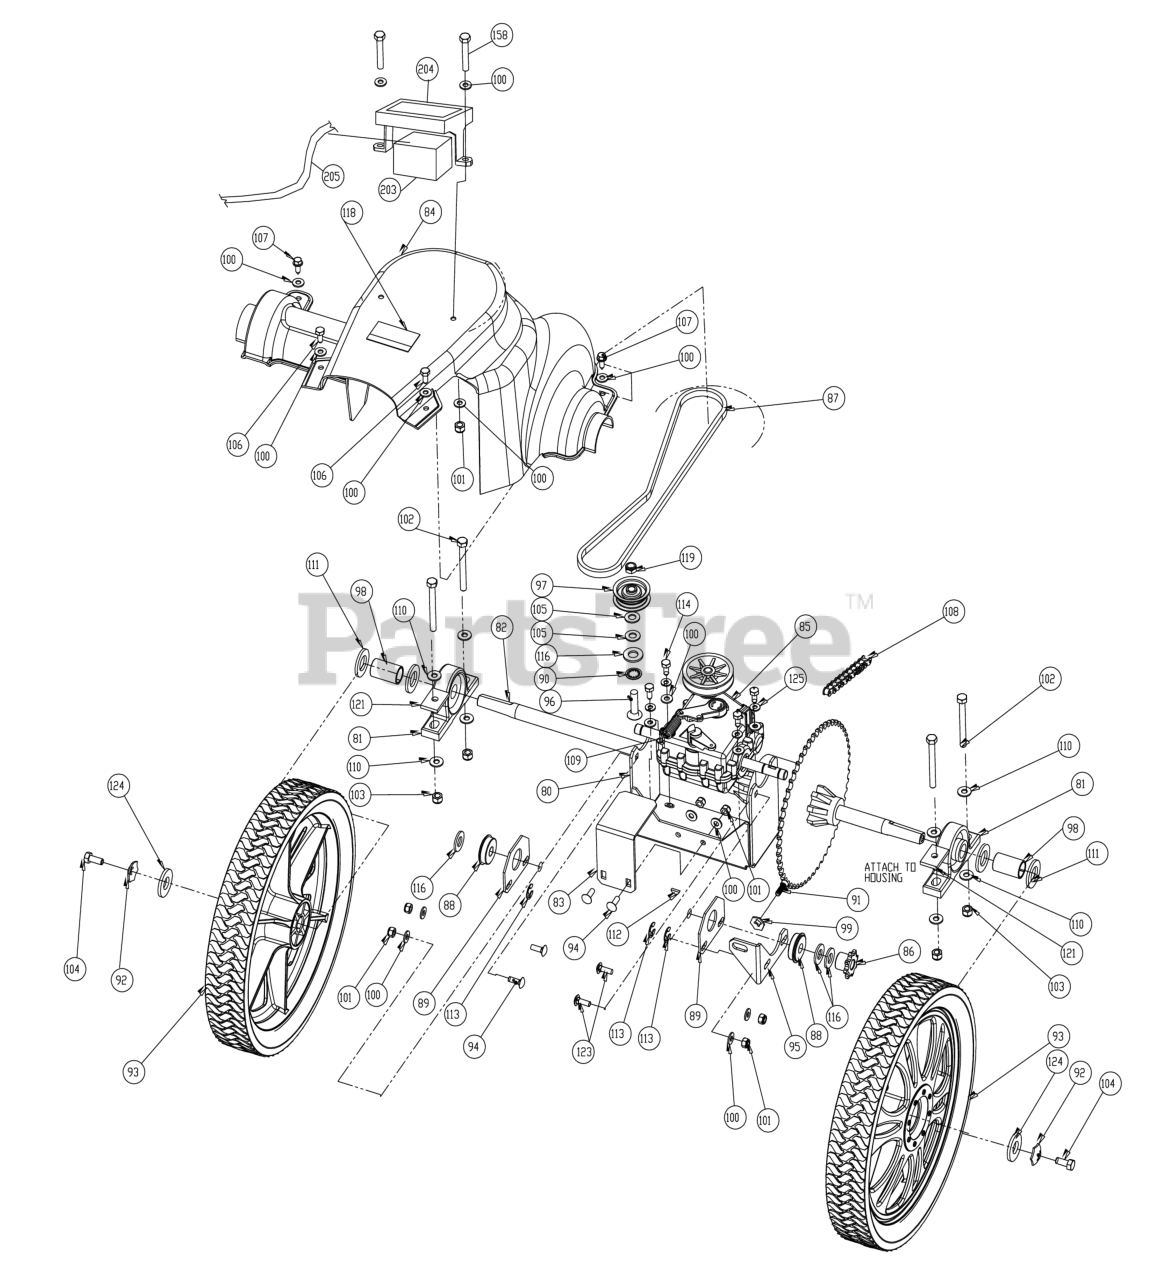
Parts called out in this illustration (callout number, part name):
80	BRACKET TRANS MOUNT WA MV VAC
81	BEARING 3/4" W/PILLOW BLOCK
82	DIFFERENTIAL 54 TOOTH D CUT
83	BRACKET TRANS ANTI ROTATE
84	GUARD COVER TRANS DRIVE
85	TRANSMISSION 3 SP GENERAL TRANS
86	SPROCKET 8 TOOTH 41B8
88	BEARING 1/2" CLIP
89	PLATE TRANS BEARING SUPPORT
90	WASHER LOCK 1/2" INTERNAL TOOTH
91	SCREWCAP 1/4"-20X3/4" HCS ZP
92	WASHER LOCK 5/16" TWISTED TOOTH HEAVY
93	WHEEL AND TIRE 14" TREADED
94	BOLT CARRIAGE 1/4" X 3/4"
95	BRACKET TRANS REINFORCE VAC
96	BOLT CARRIAGE 3/8"-16 X 1 1/2" ZP
97	PULLEY IDLER 2"OD X 3/8" ID
98	TUBE 0.75 ID WHEEL SPACER SP MV VAC
99	WASHER LOCK 1/4 TWISTED TOOTH
100	WASHER 1/4" SAE ZP
101	NYLON INSERT LOCKNUT 1/4-20 UNC
102	SCREWCAP 5/16"-18 X 3" HCS ZP
103	NUT LOCK 5/16"-18 HEX Z/P
104	SCREWCAP 5/16"-18X3/4" HCS ZP
105	WASHER 3/8"SAE 13/32"X13/16"X1/16"
106	SCREW SELF TAP 1/4"-20 X 5/8" HWH TYPE F
107	SCREW SM 1/4"X3/4" TYPE A HX WF
108	SEE: 840072-S
109	SPRING EXTENSION
110	WASHER 1/4" FLAT Z/P
111	WASHER 3/4" SAE 13/16"X1.5"X1/8"ZP
112	KEY WOODRUFF 1/8" X 1/2"
113	RING RETAINING 1/2"
114	SCREWCAP 1/4"-20 X 5/8" GR 5
116	WASHER 1/2"FC9/16"X1 3/8"X7/64"
118	LABEL DANGER
119	NUT LOCK 3/8-16 LT WT THIN ZP
121	BRACKET BEARING FIX MV
123	BOLT CARRIAGE 1/4"-20 X 1" ZP
124	WASHER FLAT FENDER 5/16
125	WASHER LOCK 1/4" S/T MED
158	SCREWCAP 1/4"-20 X 1" HCS ZP
195	BEARING 1/2 ID
203	BATTERY 12 V 5.5 AH
204	BRACKET BATTERY TRAY
205	SEE: 840275
